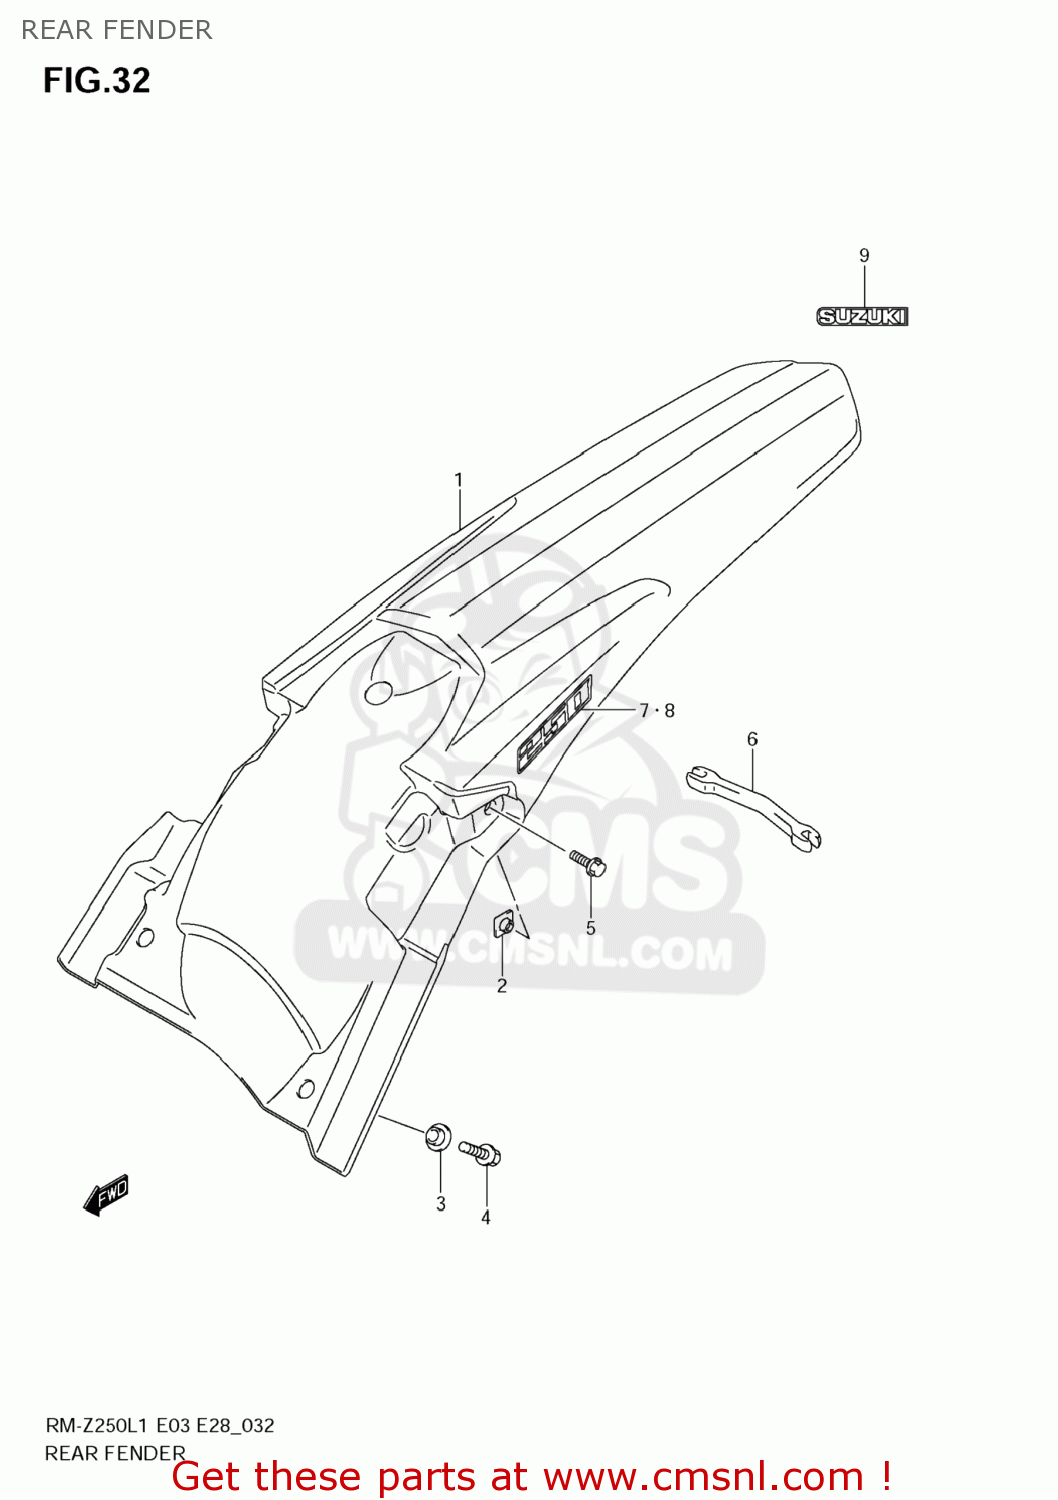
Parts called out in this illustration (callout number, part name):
1	FENDER,REAR
2	NUT,RR REFLECTOR
3	WASHER,FR FENDER
4	BOLT
5	BOLT(6X16)
6	OPEN SPANNER(6.4X6.8)
7	EMBLEM,RR FENDER,R
8	EMBLEM,RR FENDER,L
9	EMBLEM,SUZUKI
